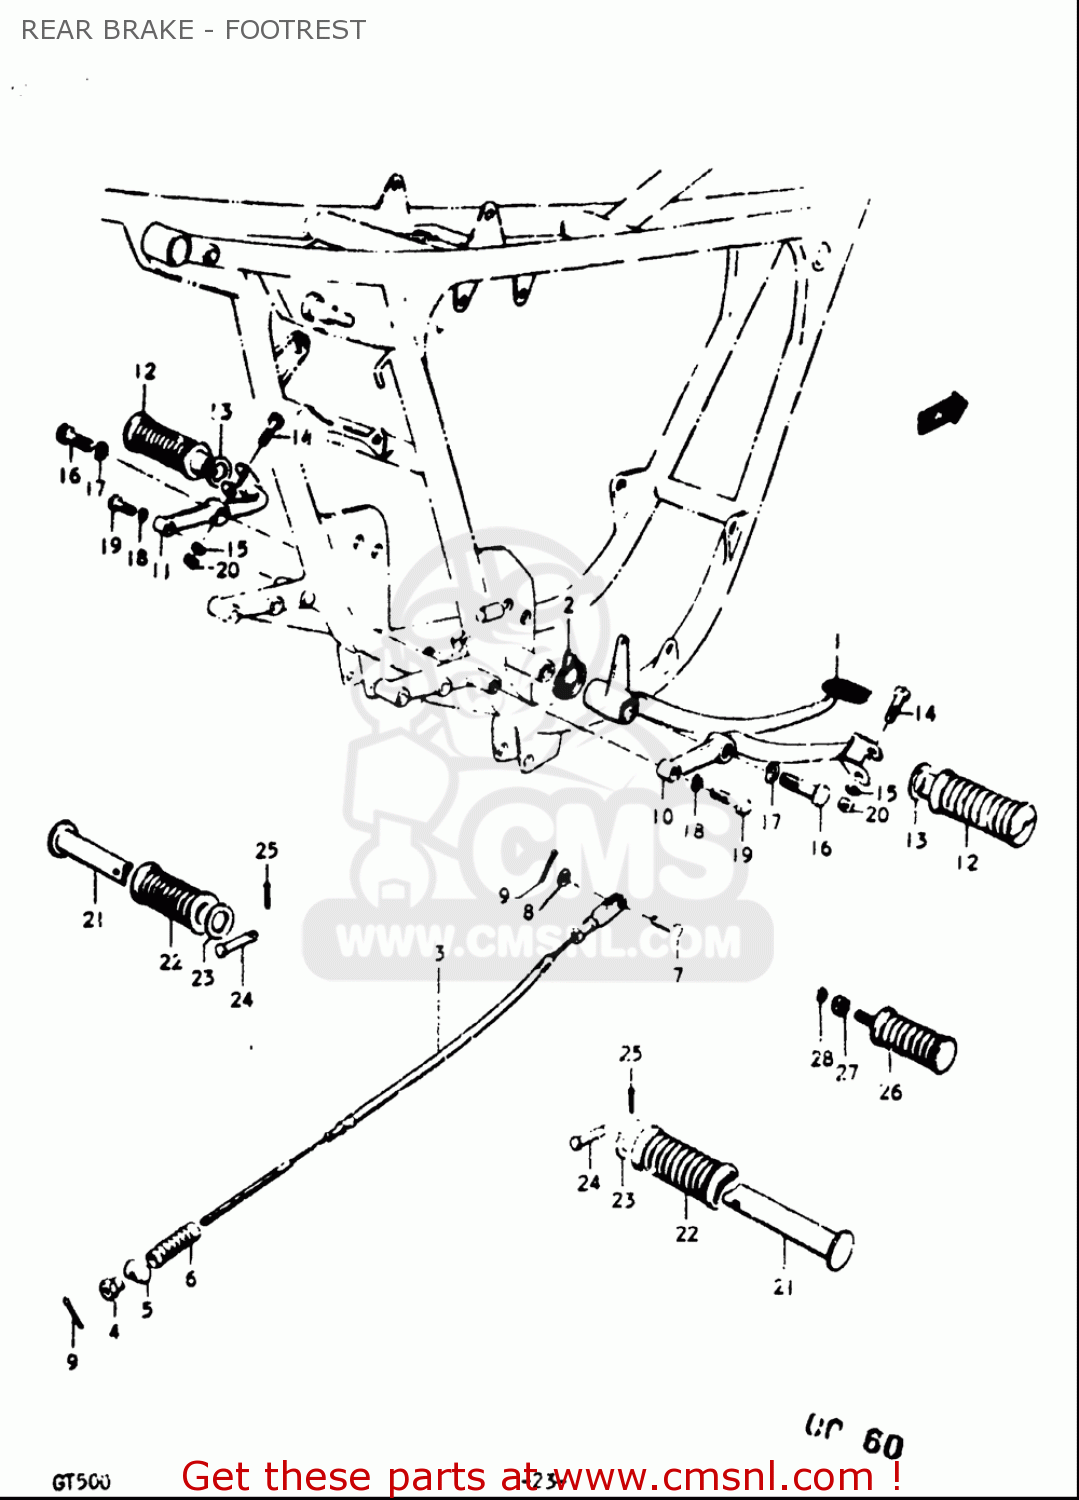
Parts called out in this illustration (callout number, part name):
21	BAR,FOOTREST RUBBER
22	RUBBER,PILLION FOOTREST
23	WASHER(19.5X32X2)
24	PIN
25	PIN
26	FOOTREST SET,PILLION
27	NUT
28	WASHER,LOCK
